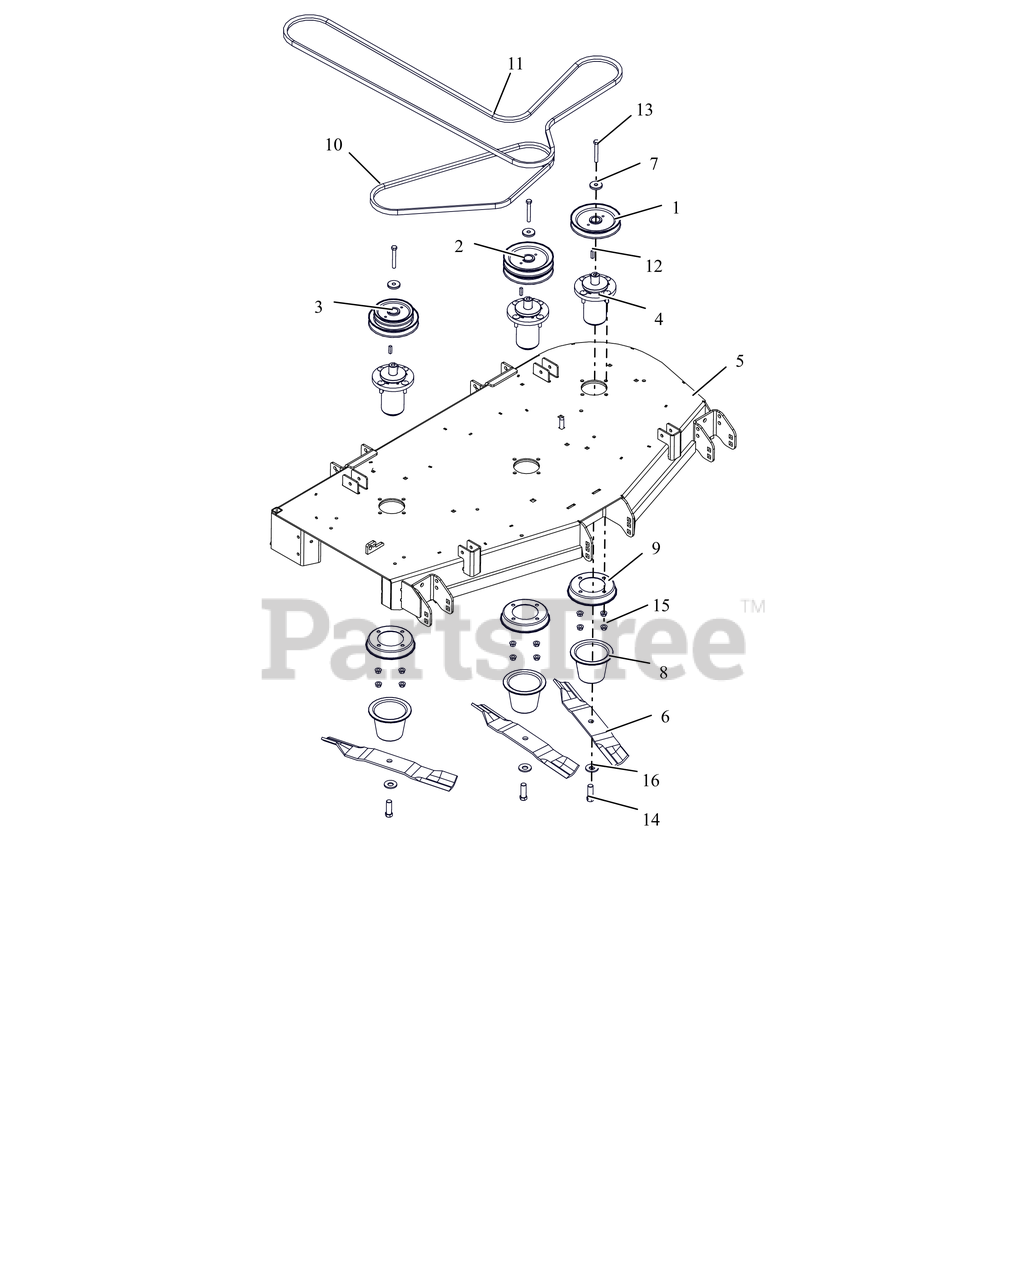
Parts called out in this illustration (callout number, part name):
1	PULLEY, SINGLE-1"ID X 6" OD
2	PULLEY, DOUBLE
3	PULLEY, DBL-1"IDX6.00"&4.75"OD
4	ASM, MAINT FREE ALUM SPINDLE
5	52"SIDE DISCH DECK WMT W/SAFE
6	BLADE, 18.00" MOWER (HI-LIFT)
7	RETAINER, SHEAVE
8	GUARD, SPINDLE LOWER
9	GUARD, SPINDLE TOP
10	V-BELT, B-COGGED
11	V-BELT, HB RAW EDGE EPDM
12	KEY, SQ .25X.25X1.00 RC 40-50
13	BLT, HEX .38-16X2.75 G8 ZCC
14	BLT, HEX .62-18X1.75 G8 ZCC
15	NUT-LK-CTR-FLG .375-16 GF ZCC
16	WSHR-BLVL .669X1.535X.138
